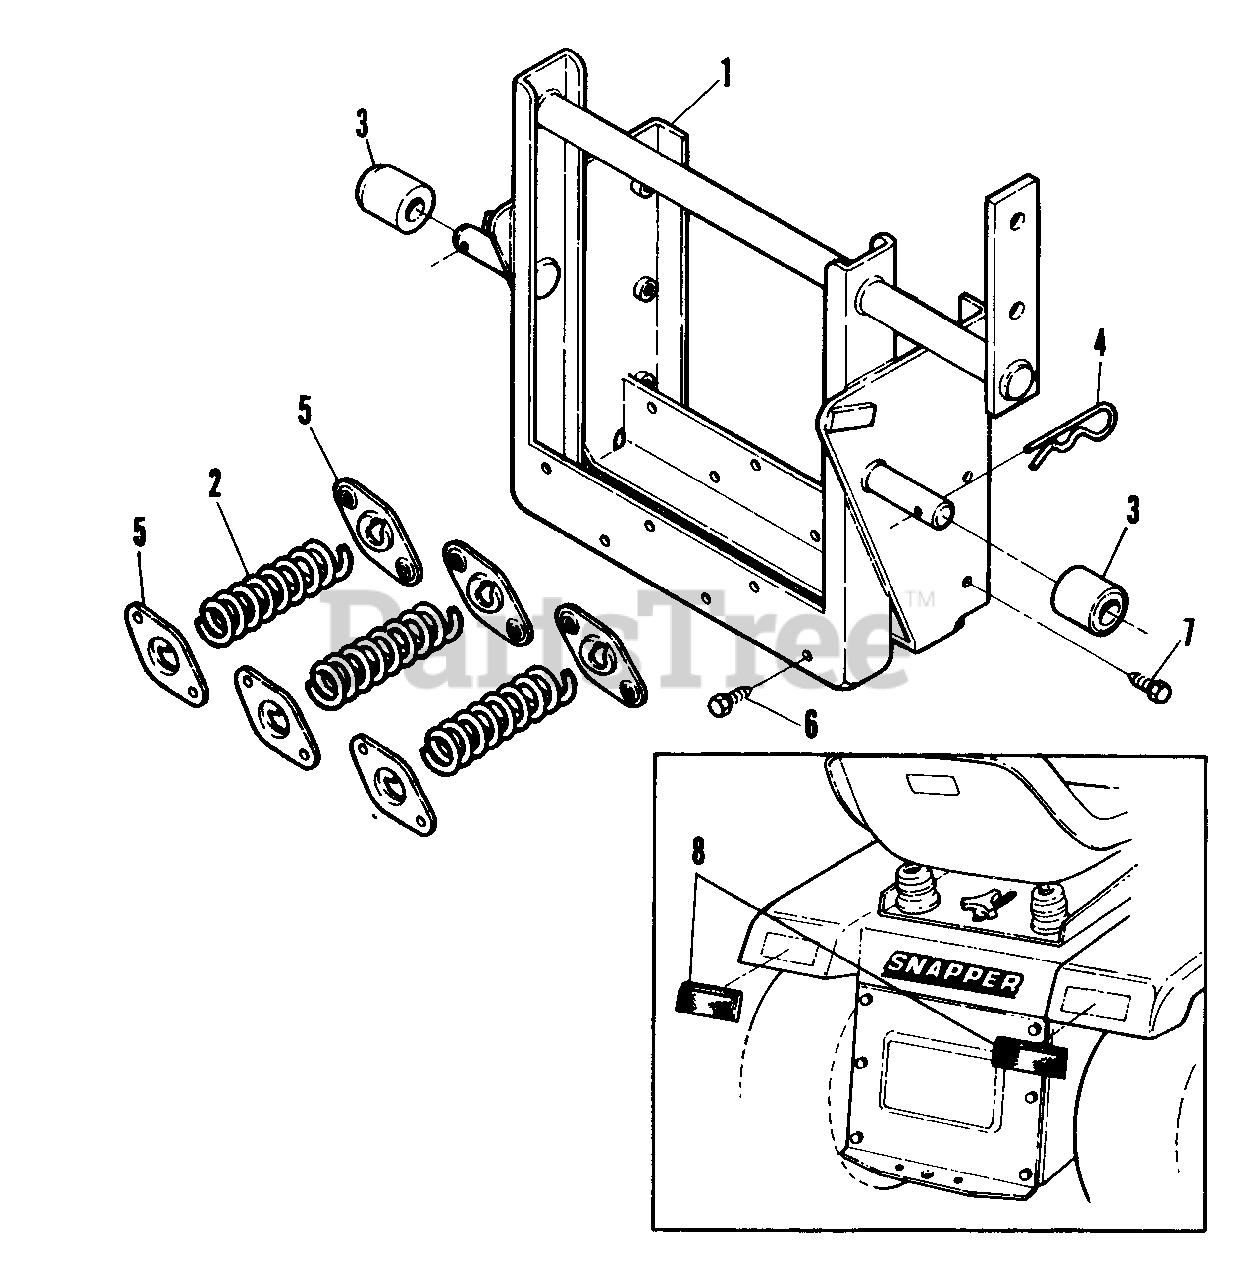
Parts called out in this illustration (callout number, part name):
1	STRUCTURE, Lift Yoke
3	BUSHING, Hitch
4	PIN, Cotter - Hair
5	RETAINER, Spring
6	SCREW, 1/4 - 20 x 1/2 Self Tap
7	SCREW, 5/16 - 18 x 3/4 Self Tap
8	REFLECTOR
